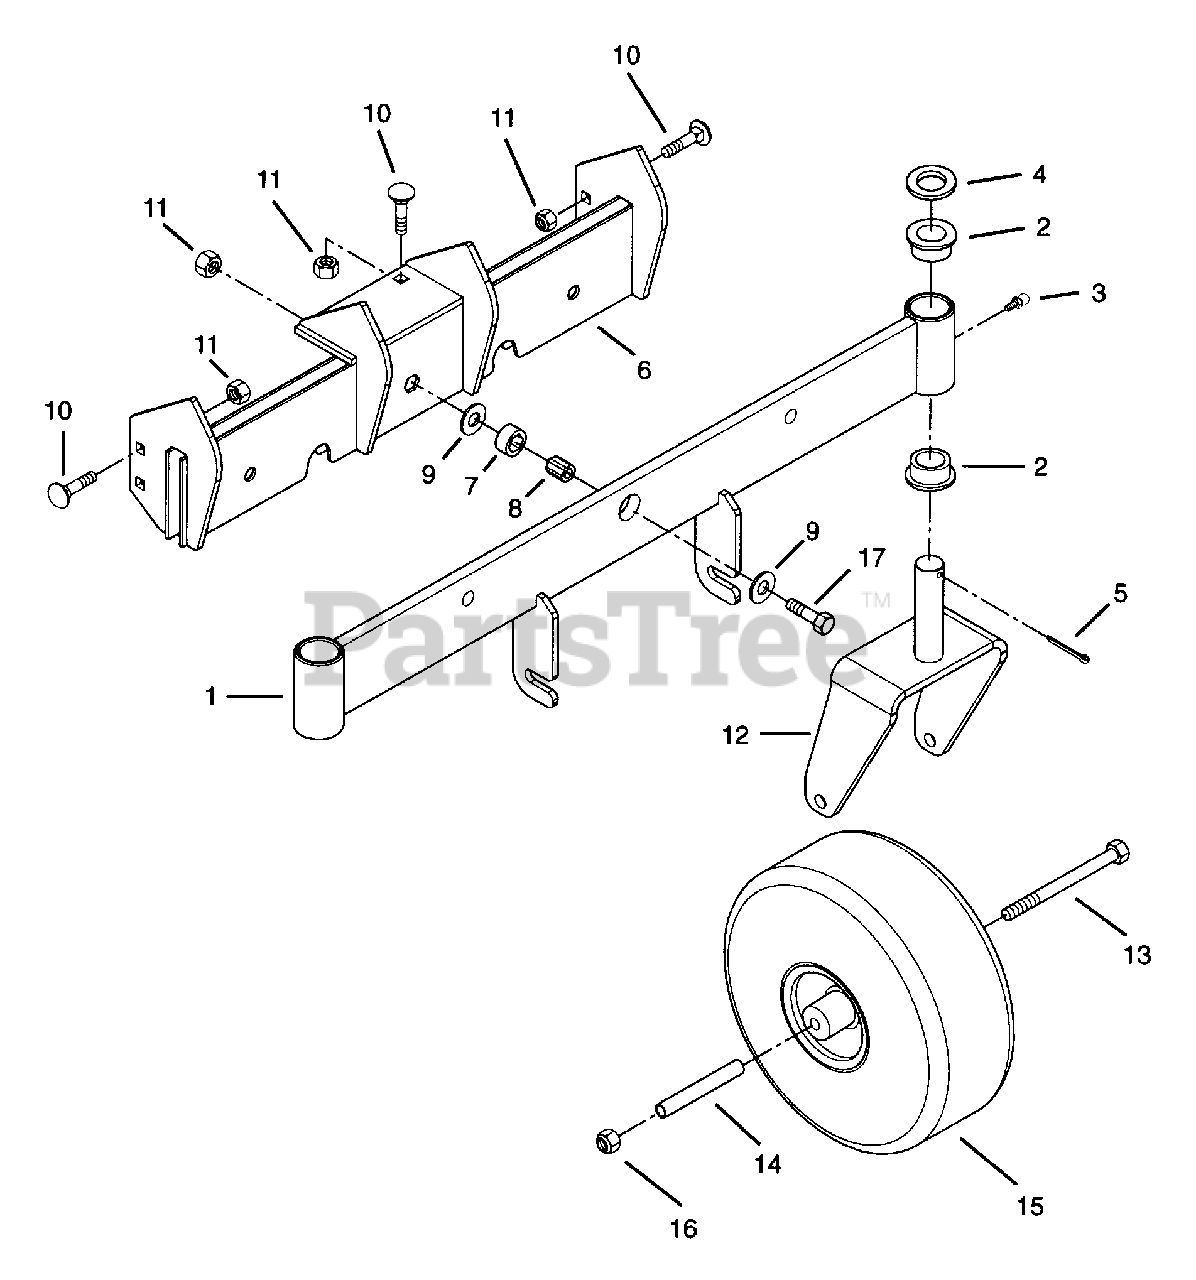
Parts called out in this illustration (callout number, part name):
1	AXLE WELDMENT
2	BSHG-FLG1.020X1.385X.75X1.75NY
3	FTG-LUBE .25-28X.256 YWZC
4	WSHR-HDND-THRUST 1.00X1.55X.03
5	PIN-COTR .188X1.50
6	AXLE FRAME WELDMENT
7	BSHG-SLV .626X1.000X.524 HEX
8	BSHG-SLV .377X.623X.775 HEX
9	WSHR-FL-STL .380X1.50X.125 PL
10	BLT-RDHDSQNK .38-16X1.0 GR5PL
11	NUT-LK-NYL .375-16 PL
12	WLDT,CASTER FORK
13	BLT-HEX .50-13X6.50
14	BUSH.,CASTER FORK
15	T/WHL 11X4.00-5 RIBBED
16	NUT-LK-NYL .50-13 GR 5 PL
17	BLT-HEX .38-16X1.75 PL GR5
